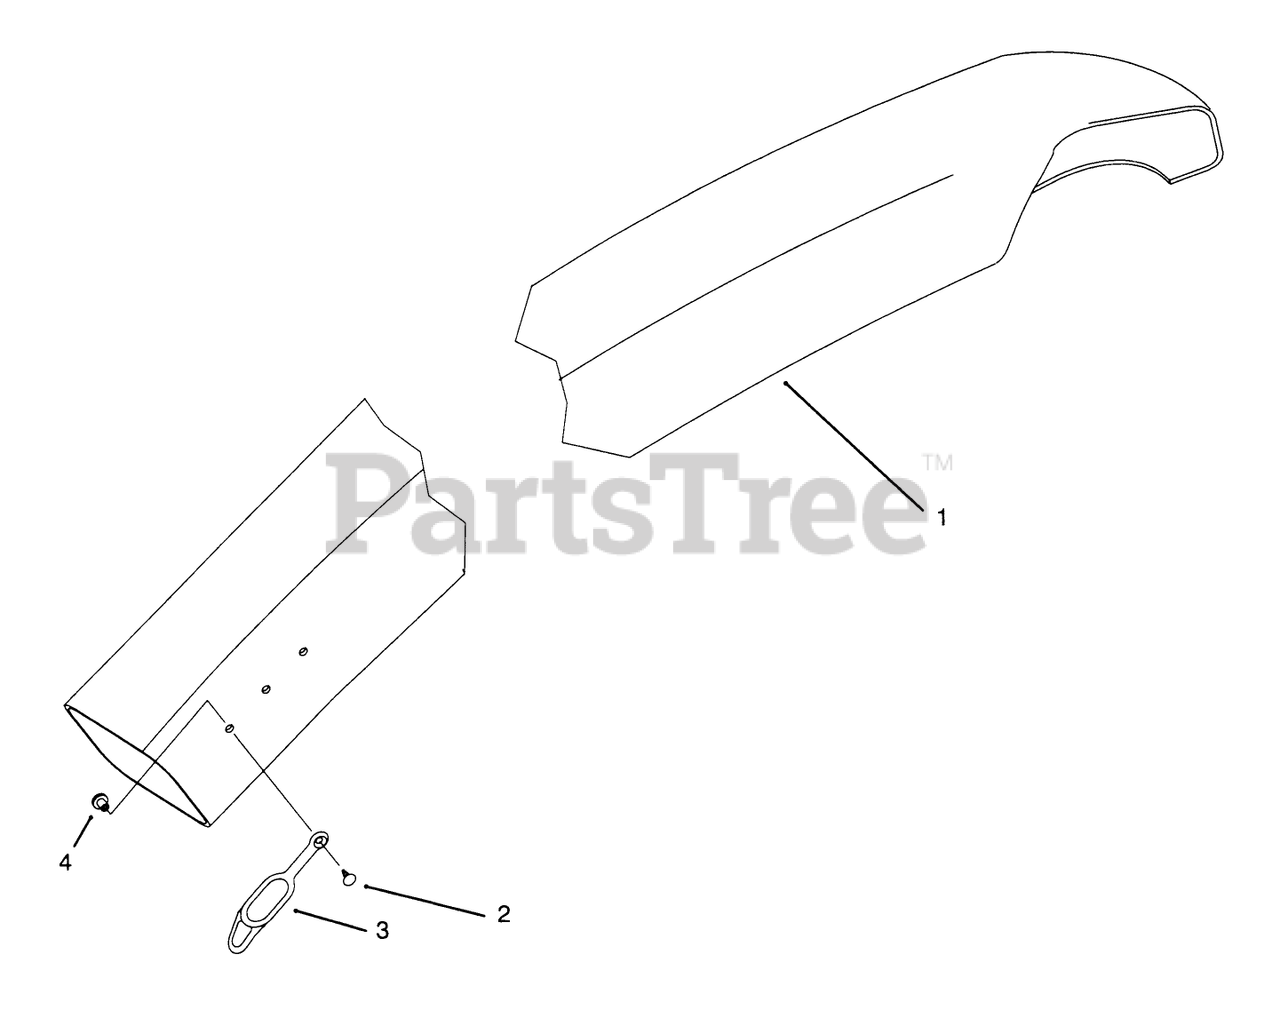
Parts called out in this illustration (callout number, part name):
1	CHUTE-DISCHARGE
2	FASTENER-PANEL
3	RETAINER-DUCT
4	SPACER-INTERLOCK
